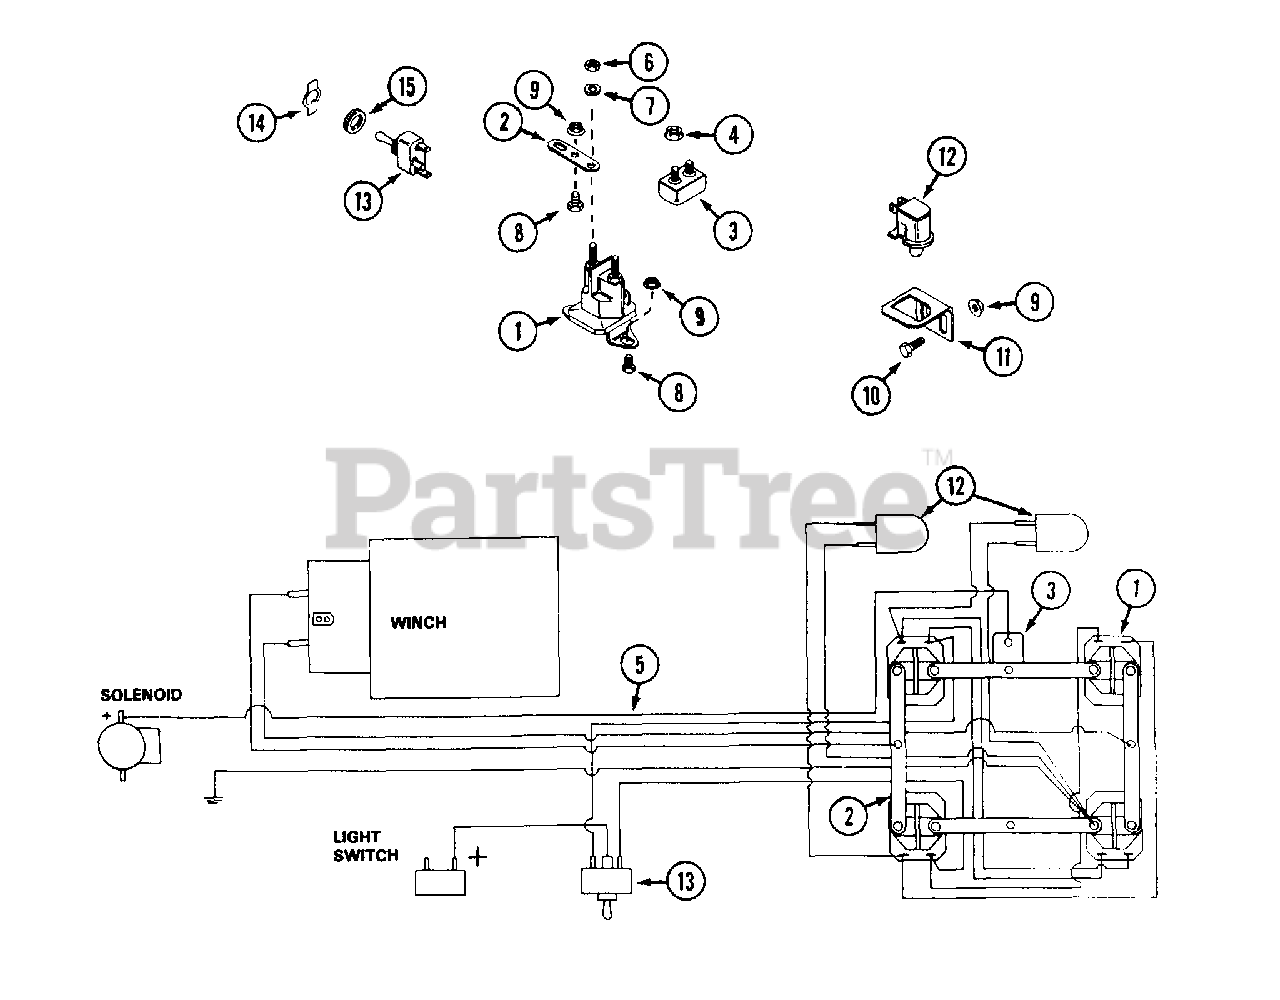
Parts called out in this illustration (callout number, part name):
1	SOLENOID - 12V
2	STRAP
3	BREAKER - 40 amp, 12V
4	NUT - #10 - 32
5	HARNESS - wire
6	NUT - 1/4" - 20
7	LOCKWASHER - 1/4"
8	BOLT - 1/4" - 20 x 1/2"
9	NUT - 1/4" - 20 flange
10	BOLT - 1/4" - 20 x 3/4"
11	BRACKET - switch
12	SWITCH - limit
13	SWITCH - lift
14	DECAL - switch identification
15	NUT - 15/32" - 32, switch
